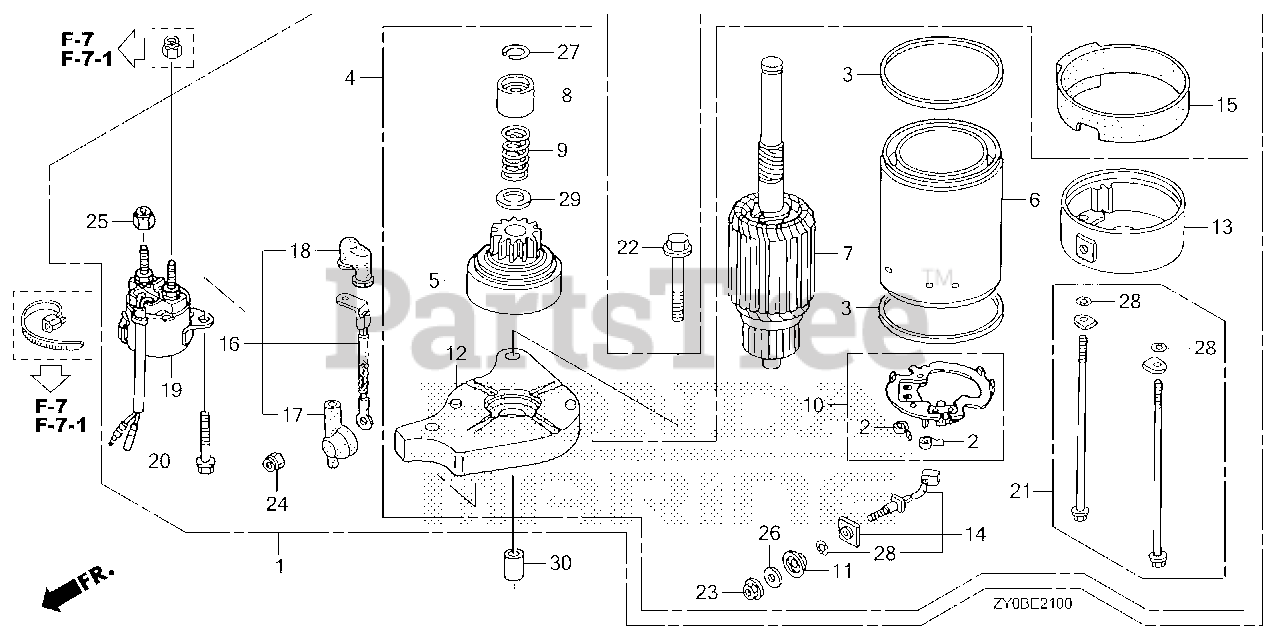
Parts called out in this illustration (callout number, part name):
1	MOTOR ASSY., STARTER
2	SPRING, CARBON BRUSH
4	MOTOR UNIT, STARTER
8	PIECE, STOPPER
9	SPRING, RETURN
10	HOLDER, BRUSH
12	BRACKET, FR.
13	BRACKET, RR.
14	UNIT, TERMINAL
15	SUSPENSION, STARTER
16	WIRE, MAGNETIC SWITCH
17	COVER, STARTER TERMINAL
18	COVER, MAGNETIC SWITCH TERMINAL
19	SWITCH ASSY., STARTER MAGNETIC
20	BOLT, FLANGE (6X14)
21	BOLT SET, SETTING
22	BOLT, FLANGE (8X45)
23	NUT-WASHER (6MM)
24	NUT, LOCK (6MM)
25	NUT, LOCK (6MM)
26	WASHER (6MM)
27	CIRCLIP (14MM)
28	O-RING
30	PIN, DOWEL (10X12)
